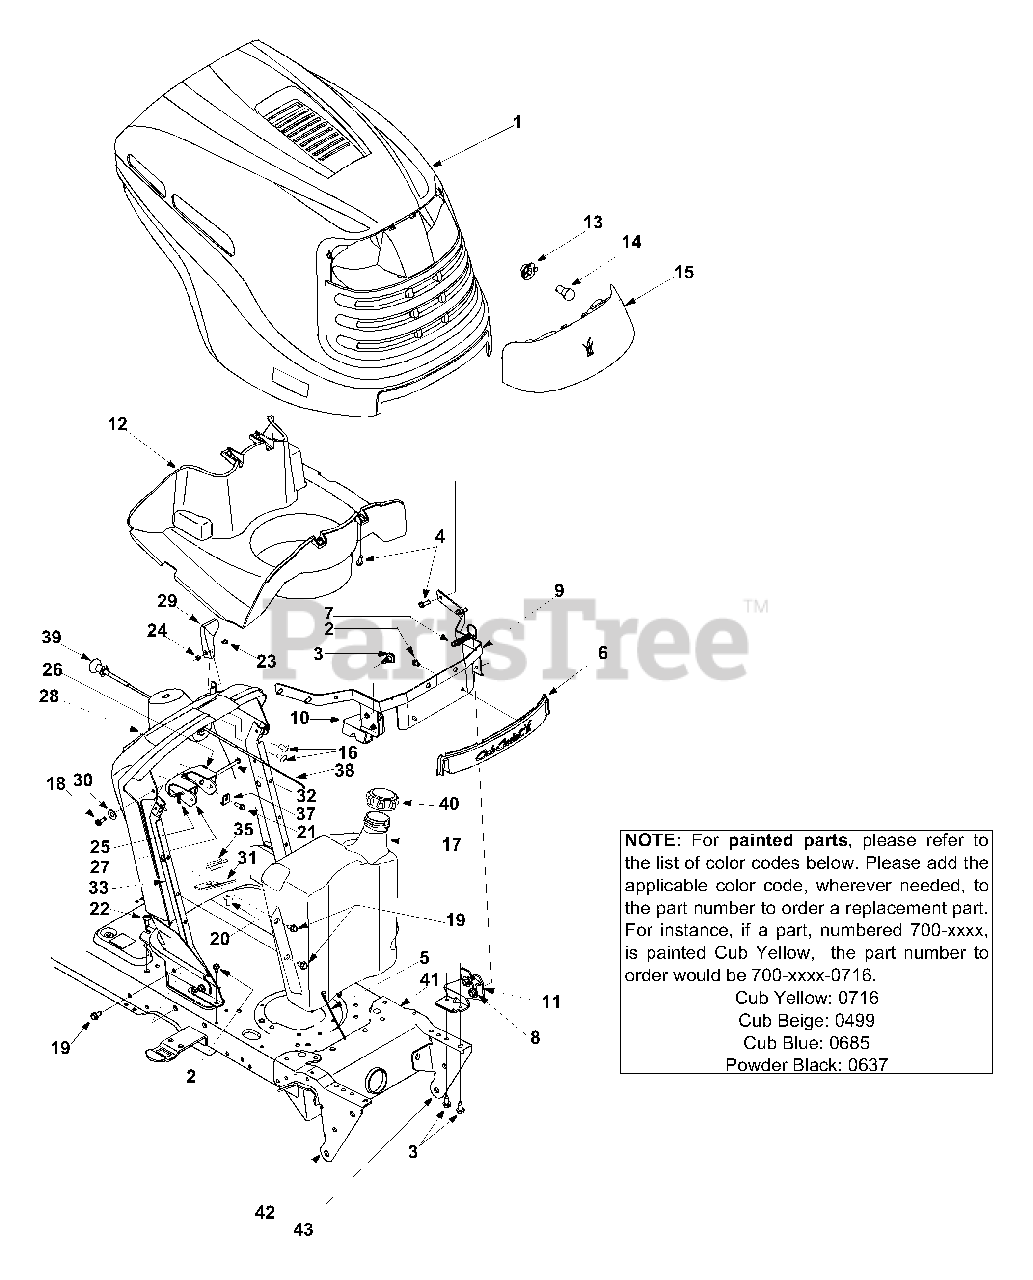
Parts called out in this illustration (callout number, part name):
1	Hood
2	TT Screw 1/4-20 x 0.5
3	AB Screw 5/16-12 x 0.75
4	Hi-Lo Screw 1/4-15 x 0.75
5	Cable Tie
6	Cover: Front Hood
7	Extension Spring
8	Shoulder Screw 5/16-18
13	Lamp Socket
14	Lamp 12 V
15	Headlight Lens
16	Mach. Screw
17	Fuel Tank: 3 Gallon
18	TT Screw 1/4-20 x 0.75
19	AB Screw 5/16-12 x 0.75
20	Oval C-Sunk AB Screw
21	Hi-Lo Screw 1/4-15 x 0.75
22	TT Screw 5/16-18 x 0.75
23	Mach. Screw
25	Cotter Pin
26	Brake Lever: Dash
27	Cruise Lever: Dash
28	Dash
29	Throttle Control Knob
30	Flat Washer
31	Steering Column
38	Throttle Cable 39" LG
39	Choke Control
40	Fuel Cap
